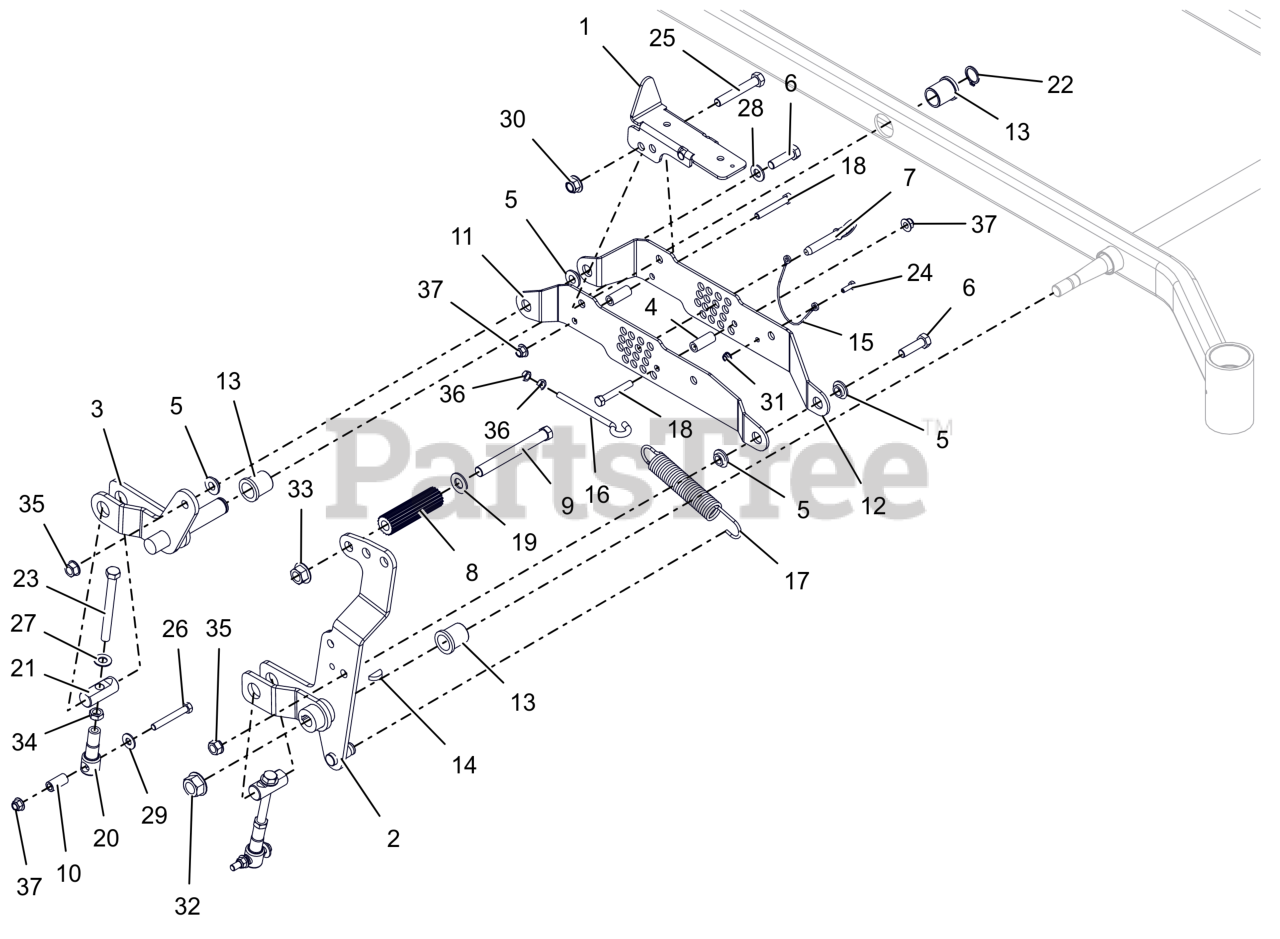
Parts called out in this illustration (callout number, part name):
1	MECHANICAL LOCK-UP WMT - BLACK
2	FRT RH DECK LIFT ARM WMT- LF
3	REAR RH DECK LIFT ARM WMT- LF
4	SPACER, .375 X .625 X 1.54
5	BSHG-FLG .515X.750X.310X1.120
6	BLT, HEX .50-13X1.75 G5 ZCC
7	PIN, .50 X 2.00 USABLE LG BALL
8	ROD, FOOT PEDAL (BLACK)
9	BLT, HEX .62-11X5.50 G5 FBP
10	SPACER, DECK LEVELING
11	RH OTBRRD LIFT/CUT HT BRKT-BLK
12	RH INBRD LIFT/CUT HT BRKT-BLK
13	BSHG-FLG 1.00X1.25X1.50X1.50
14	KEY-WDRF .25X1.00 HRD #15
15	CABLE, 12.0 LANYARD, NYLON
16	BOLT,.38-16 X 4.25-.62 DIA EYE
17	SG-TENS .162X1.25X8.25 WLD 25
18	BLT, HEX .38-16X2.50 G5 ZCC
19	WSHRFLT 5/8SAE CARBHARD FBP
20	LINK, DECK LIFT FORMED
21	PIN, DECK LIFT
22	RG-RTNG-EXT 1.00X.078
23	BLT, HEX 0.5-13X5S GR5 ZCC
24	BLT, HEX .25-20X.75 G5 ZCC
25	BLT,HEX .50-13X3.25 G5 ZCC
26	BLT, HEX .38-16X2.75 G8 ZCC
27	WSHR, FLT .557X1.040X.102 ZCC
28	WSHR,FLT .531X1.062X.095 ZCC
29	WSHR,FLT .438X1.00X.083 ZCC
30	NUT,NYL-FLG .50-13 GF ZCC
31	NUT,NYL-FLG .25-20 GF ZCC
32	NUT,FLG-TOP LK .625-11 FBP
33	NUT,FLG-TOP LK .625-11 FBP
34	NUT-JAM .500-13 G2 ZCC
35	NUT-LK-CTR-FLG .500-13 GG ZCC
36	NUT-JAM .375-16 G2 ZCC
37	NUT,NYL-FLG .38-16 GF ZCC
